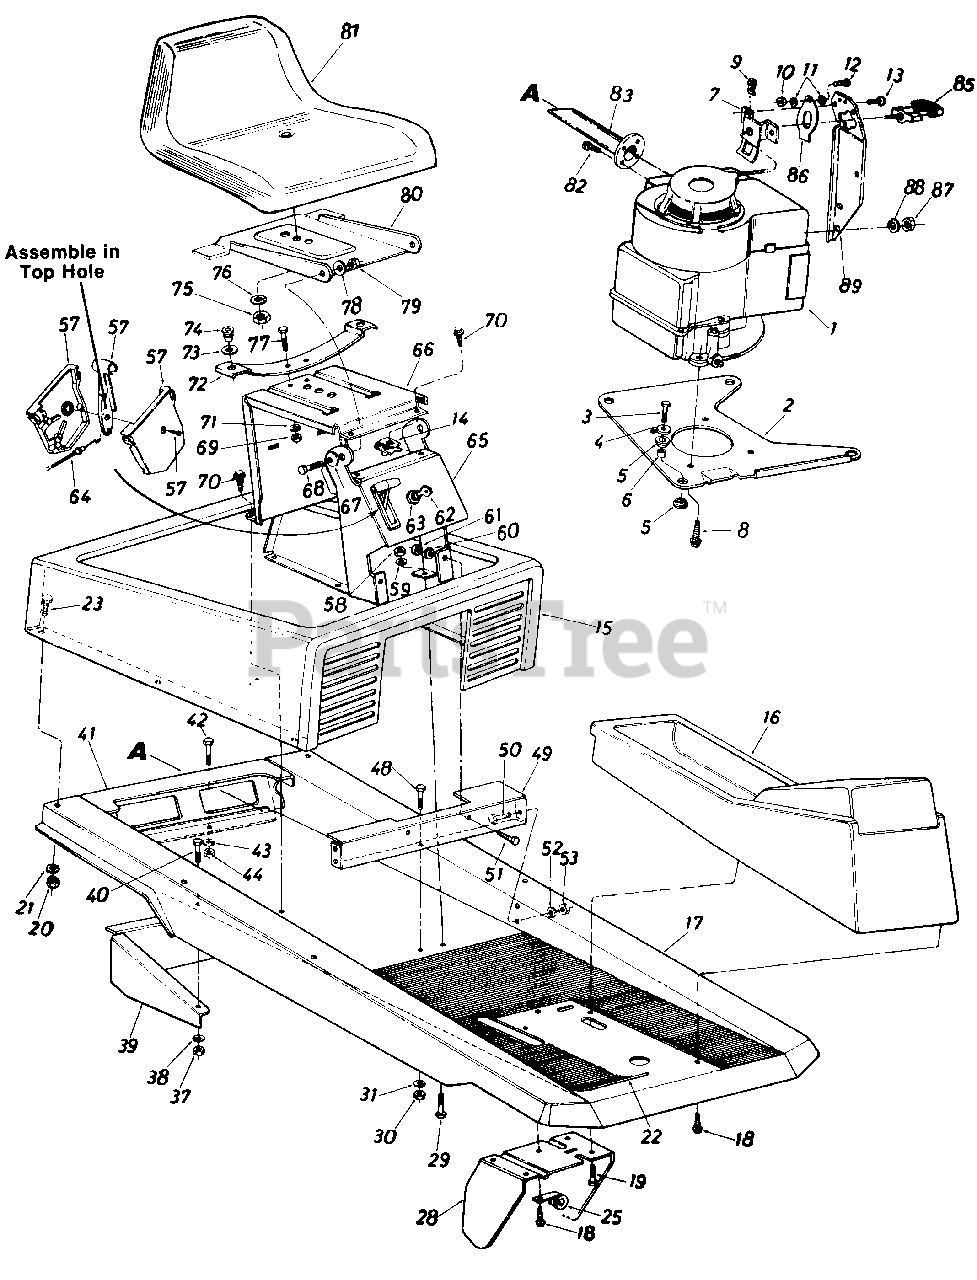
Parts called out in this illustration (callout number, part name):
1	Engine
2	Engine Mounting Plate
3	Hex Bolt 5/16-24 x 1.25" Lg.
4	Fl-Wash. .330" I.D. x 1.125" O.D.
5	Engine Mounting Grommet
6	Spacer.315" I.D. x .50" O.D. x .520" Lg.
7	Switch Brk't. Ass'y.
8	Hex Wash. Hd. Self-Tap Scr. 3/8-16 x 1.25" Lg.
9	Speed Nut #10-24 U-Type
10	Hex Nut #10-24 Thd.
11	Fiber Washer
12	Truss Mach. Scr. #10-24 x .62" Lg.
13	Truss Mach. Scr. #10 x .50" Lg.
14	Palnut Lug 5/16-18 Thd.
15	Engine Cover Ass'y.
16	Front Console
17	Main Frame
18	Plastite Scr. 5/16 x 1.25" Lg.
19	Hex Bolt 5/16-18 x .75" Lg.
20	Hex Nut 1/4-20 Thd.
21	L-Wash. 1/4" I.D.
22	Floor Mat
23	Hex Bolt 1/4-20 x .50" Lg.
25	Clamp
28	Clutch-Brake Pedal Ass'y.
29	Hex Bolt 5/16-18 x .62" Lg
30	Hex Nut 5/16-18 Thd.
31	L-Wash. 5/16" I.D.
37	Hex Nut 5/16-18 Thd.
38	L-Wash. 5/16" I.D.
43	L-Wash. 5/16" I.D.*
44	Hex Nut 5/16-18 Thd.
48	Hex Bolt 5/16-18 x .75" Lg.
49	Seat Support & Frame Brk't.
50	Hex Bolt 5/16-18X .50" Lg.
51	Hex Bolt 5/16-18 x .50" Lg.
52	L-Wash. 5/16" l.D.
53	Hex Nut 5/16-18 Thd.
57	Throttle Control Box Ass'y.
58	Hex Nut 5/16-18 Thd.
59	L-Wash. 5/16" I.D.
60	L-Wash. 5/16" I.D.
61	Hex Nut 5/16-18 Thd.
62	Ignition Key
63	Ignition Switch
64	Throttle Control Wire
65	Front Seat Bracket
66	Rear Seat Bracket
67	Bell-Wash. .345" I.D. x .88" O.D.
68	Hex Bolt 5/16-18 x .75" Lg.
69	Hex Nut 5/16-18 Thd.
70	Hex Wash. Self-Tap Scr. 5/16-18 x .75 Lg.
71	L-Wash. 5/16 n l.D.
72	Seat Spring
73	Fl-Wash. .531" I.D. x .930" O.D.
74	Grommet
75	Hex Nut 1/2-13 Thd.
76	L-Wash. 1/2" I.D.
77	Hex Bolt 5/16-18 x .62" Lg.
78	Bell-Wash. .345" I.D. x .88" O.D.
79	Hex Cent. L-Nut 5/16-18 Thd.
80	Seat Pivot Bracket
81	Seat Ass'y. Comp.
82	Hex F-Tap Scr. 8-32 x .38"
83	Exhaust Pipe Ass'y.
85	Plastic Handle
86	Switch Spring
87	Hex Nut 5/16-18 Thd.
88	L-Wash. 5/16" I.D.
89	Rope Handle Bracket
